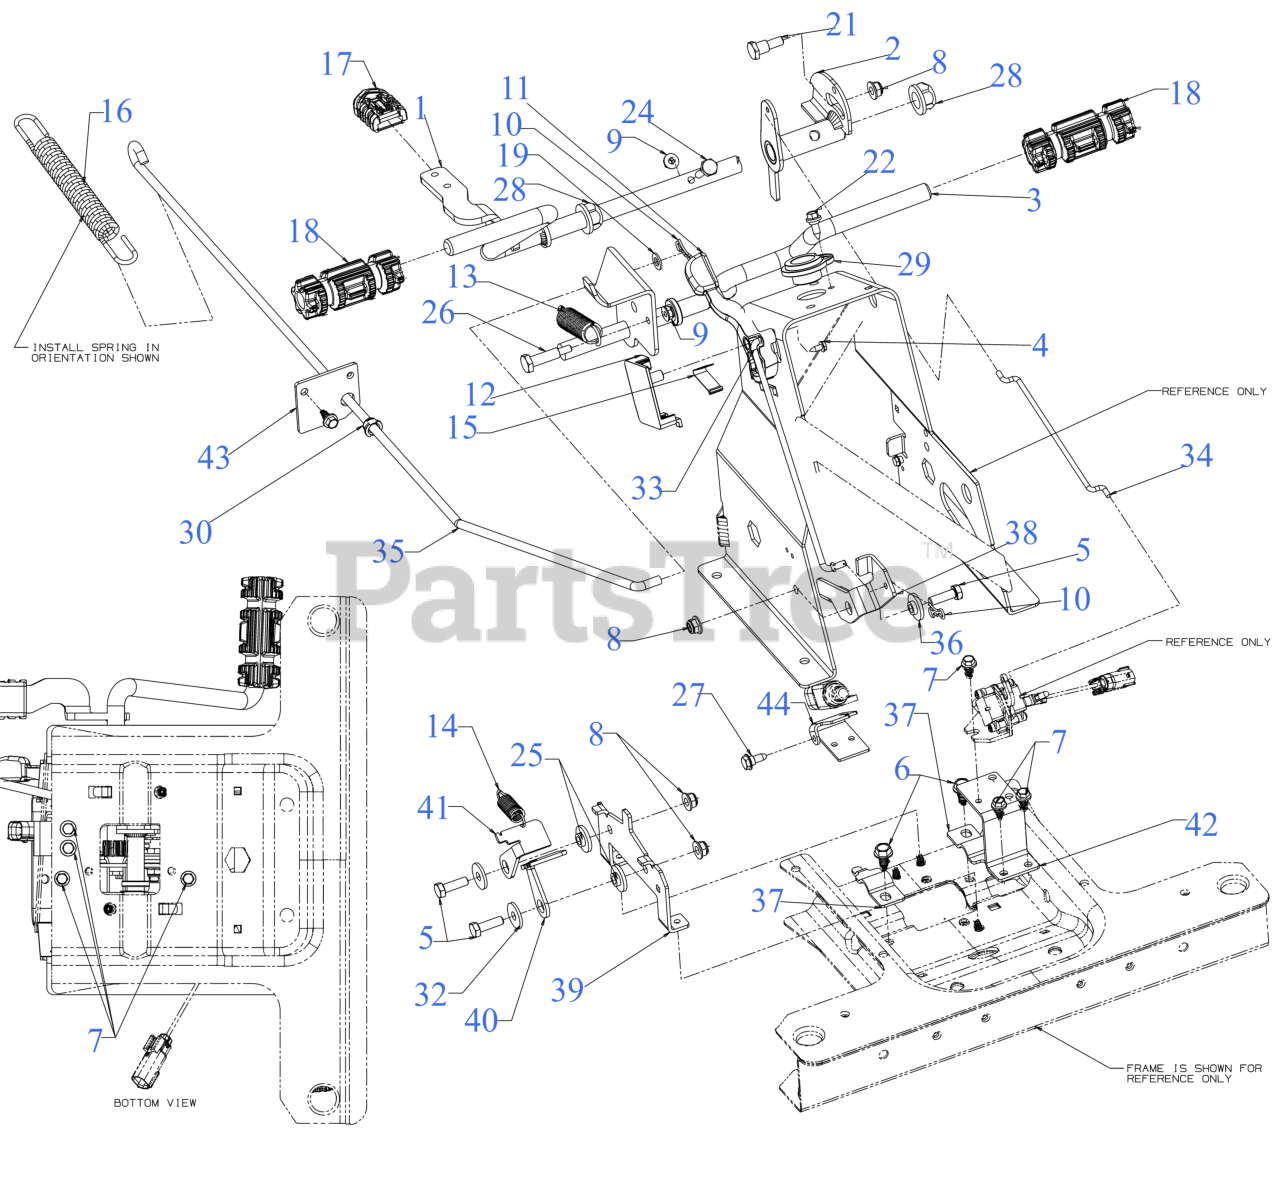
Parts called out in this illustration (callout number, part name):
2	PEDAL ASSEMBLY
3	BRAKE PEDAL ASSEMBLY
4	HEX SCREW AB-TAP #10 x .50
5	SCREW 5/16-18 x 1.0 GR5
6	SCREW 5/16-18 x .750
7	SCREW 1/4-20X.625
8	FLANGE LOCK NUT 5/16-18
9	FLANGE LOCK NUT
10	BOW TIE COTTER PIN 1/4-5/16
11	PARK BRAKE LEVER
12	SPEED CONTROL COVER
13	EXTENSION SPRING
14	EXTENSION SPRING
15	SHIFT SPRING
16	EXTENSION SPRING 0.90 DIA x 8.14
17	REVERSE PEDAL PAD
18	BRAKE PEDAL PAD
19	FLAT WASHER .344 x .62
21	SHOULDER SCREW 5/16-18 x .62 GR2
22	SHOULDER SCREW
24	SHOULDER SCREW .375 x .148
25	SHOULDER SPACER (.315" x .50" x.14")
26	SHOULDER SCREW
27	SHOULDER SCREW .31
28	FLANGE BEARING
29	FLANGE BEARING
30	BUSHING .380 ID
32	THRUST BEARING (.323" x .985" x .1")
33	SPEED SELECT ROD
34	SWITCH ROD
36	SHOULDER SPACER
37	BRAKE SHAFT STRAP
38	PARK BRAKE BRACKET
40	REVERSE RETURN BRACKET
41	FORWARD RETURN BRACKET
